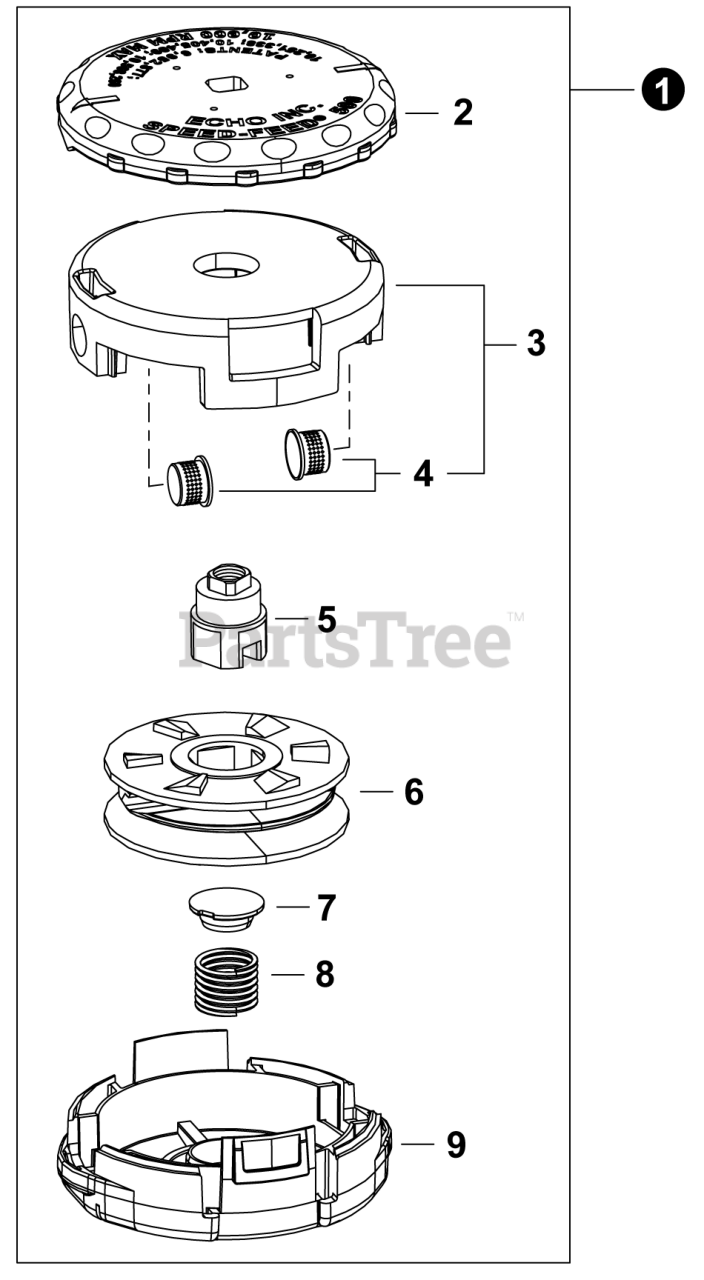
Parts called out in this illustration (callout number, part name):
1	TRIMMER HEAD, SPEED-FEED® 500
3	HOUSING ASSY, SPOOL
5	BUSHING 10MMx1.25 LH
6	SPOOL LH
7	CAP, SPRING
8	SPRING, GOLD
9	COVER, SPOOL
